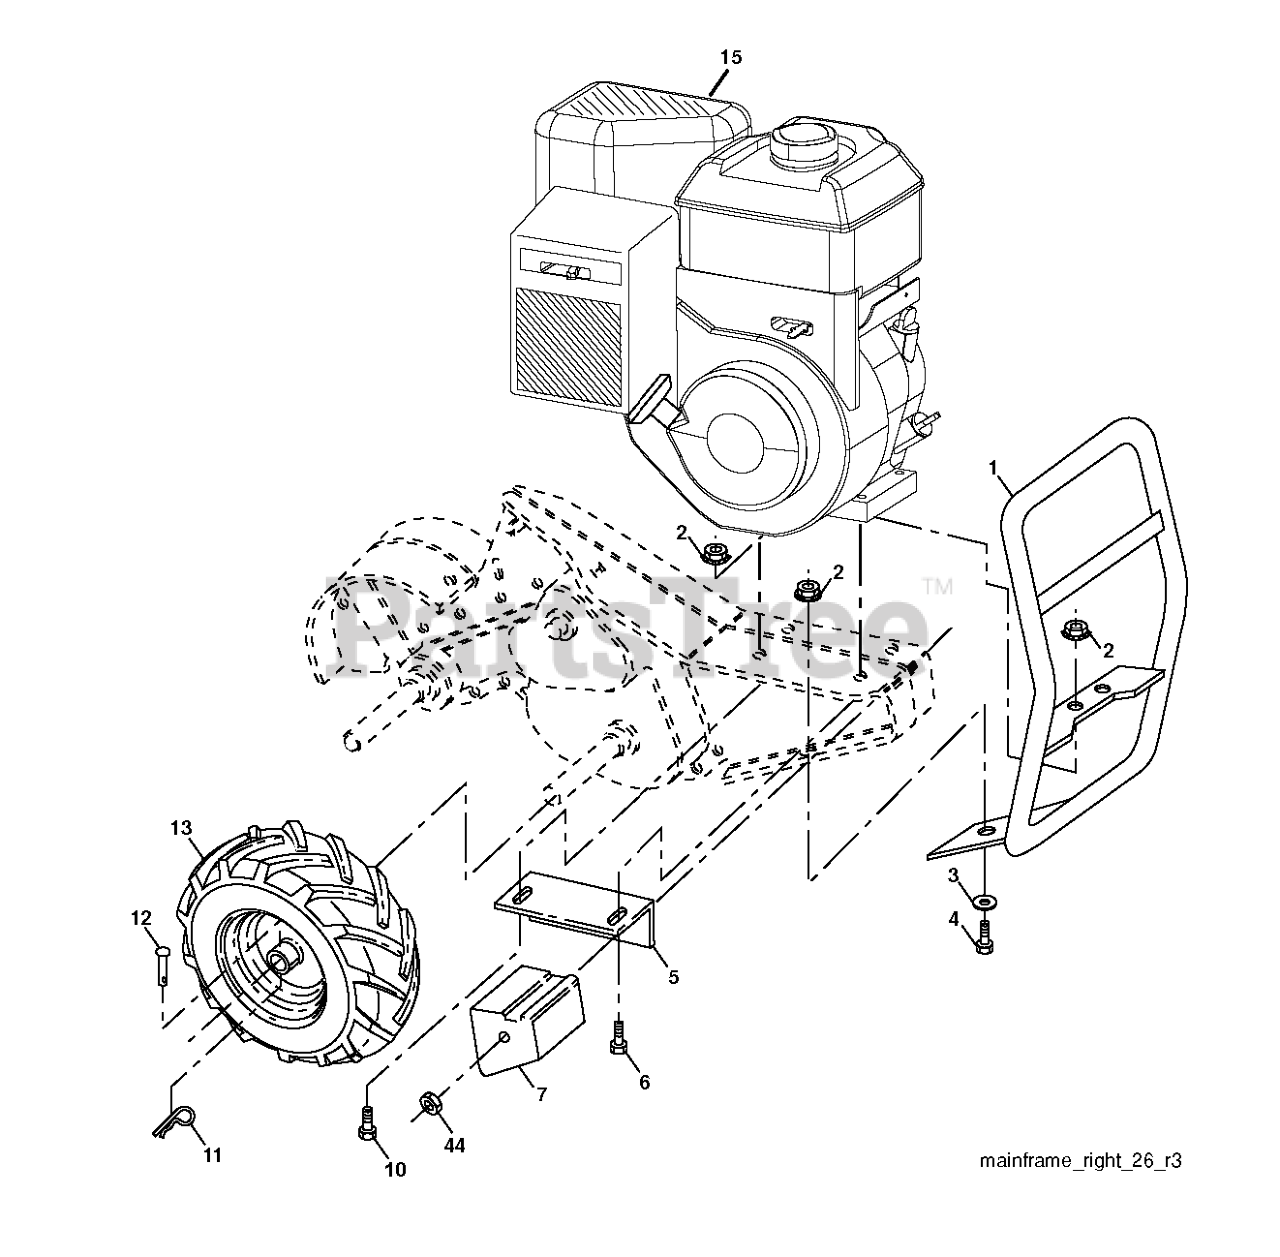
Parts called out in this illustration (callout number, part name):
1	BUMPER.ASM.TILLER.BLACK
2	LOCKNUT-FLANGE 5/16-18
3	WASHER
4	BOLT
5	BRACKET.REINFORCEMENT.RH.BLACK
6	BOLT, HEX 5/16-18X1-3/4
7	COUNTERWEIGHT.RH
10	BOLT
11	RETAINER M
12	RIVET
13	WHEEL.ASM.DRT.13X5-6.RT.SILVER
